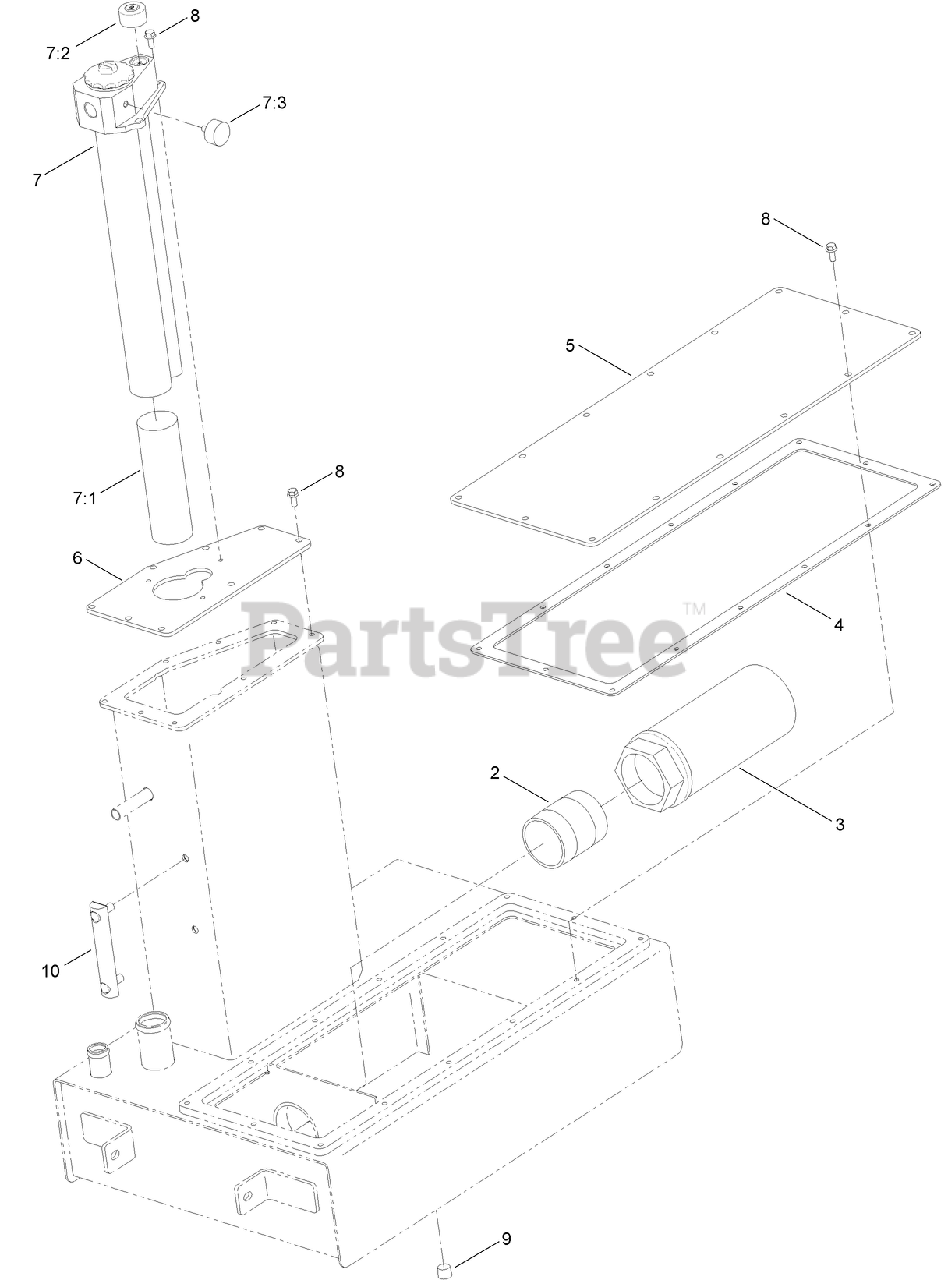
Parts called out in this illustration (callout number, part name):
2	NIPPLE-PIPE
3	STRAINER-SUCTION, 100 MESH
4	GASKET-COVER LID, HYDRAULIC TANK
5	COVER-TANK, HYDRAULIC
6	PLATE-LID, HYDRAULIC TANK
7	FILTER ASM (HYDRAULIC TANK)
7:1	FILTER-TANK, HYDRAULIC
7:2	BREATHER-FILTER, HYDRAULIC
7:3	Indicator-Visual
8	SCREW-HHF
9	PLUG-PIPE, HEX SOCKET
10	GAUGE-LEVEL, FLUID (W/THERMOMETER)
